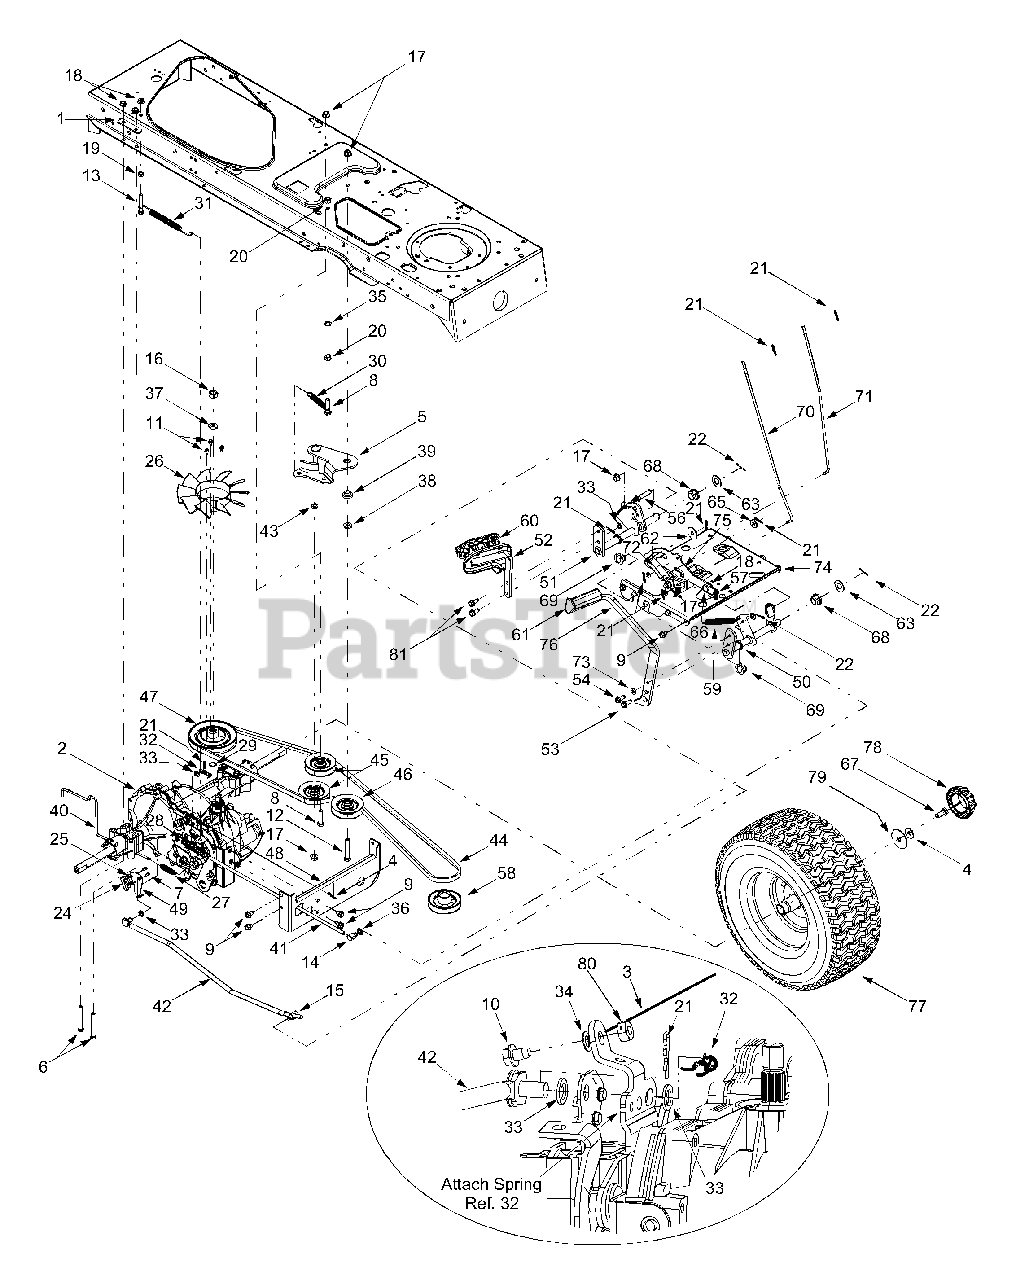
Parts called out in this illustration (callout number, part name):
1	Transaxle Mounting Bracket
2	Hydrostatic Transmission
3	Reverse Wire Harness Adapter & Ground
4	Bell Washer,.34 x.872
5	Double Idler Bracket Assembly
6	Hex Cap Screw, 5/16-18 x 2.75
7	Screw, #8-18 x.5
8	Hex Cap Screw, 3/8-16 x 1.5
9	Self-tapping Screw, 5/16-18 x.625
10	Self-tapping Screw, 1/4-20 x.375
11	Screw, #12-24 x.375
12	Hex Cap Screw, 3/8-16 x 2.25
13	Hex Cap Screw, 5/16-18 x 2.0
14	Ferrule, 5/16-18
15	Ferrule, 3/8-24
16	Hex Nut, 1/2-20
17	Flange Lock Nut, 3/8-16
18	Flange Lock Nut, 5/16-18
19	Hex Nut, 5/16-18
20	Hex Nut, 3/8-16
21	Internal Cotter Pin
22	Cotter Pin
24	Short Spring Switch
25	Insulator Nut Plate
26	10-inch Fan
27	Extension Spring,.48 x 2.03
28	Extension Spring,.59 x 4.0
29	Wire Ring
30	Extension Spring,.5 x 3.97
31	Extension Spring,.5 x 7.0
32	Extension Spring, 3/8 x 1.44
33	Flat Washer,.385 x.62 x.063
34	Flat Washer,.281 x.50 x.063
35	Lock Washer, 3/8
36	Flat Washer,.344 x.688 x.065
37	Lock Washer, 1/2
38	Flat Washer,.407 x.812 x.135
39	Shoulder Spacer,.38
40	Hydrostatic Bypass Rod
41	Hydrostatic Brake Rod
42	Hydrostatic Control Rod
43	Spacer,.376 x.625 x.22
44	Drive Belt, A x 79.10
44	Drive Belt, A x 78
45	V-idler Pulley, 3.06
46	Flat Idler Pulley, 2.75
47	Input Pulley, 5.0
48	Transmission Torque Bracket
49	Switch Actuator Bracket
50	Brake Control Assembly
51	Drive Control Assembly
52	Hydro Pedal Assembly
53	Self-tapping Screw, 5/16-18 x.875
54	Self-tapping Screw, 5/16-18 x.75
56	Pin, 3/8-16 x 2.43
57	Compression Spring,.405 OD x 1.17
58	Engine Pulley with Electric PTO, Single
59	Extension Spring,.50 OD x 6.37
60	Drive Pedal Pad
61	Brake Pedal Pad
62	Flat Washer,.411 x 1.25 x 1.0
63	Flat Washer,.64 x 1.24 x.06
65	Flat Washer,.406 x.875 x.105
66	Shoulder Screw,.437 x 1.62
67	Hex Cap Screw, 5/16-24 x.75
68	Hex Flange Bearing
69	Split Hex Flange Bearing
70	Cruise Control Rod
71	Brake Lock Control Rod
72	Cruise Latch
73	Flat Washer,.344 x.750 x.120
74	Steering Support Bracket
75	Drive Lockout Bracket
78	Deluxe Hub Cap
79	Flat Washer,.350 x 1.59 x.062
80	Hex Lock Nut, 1/4-20
81	Screw, 5/16-18 x.750
